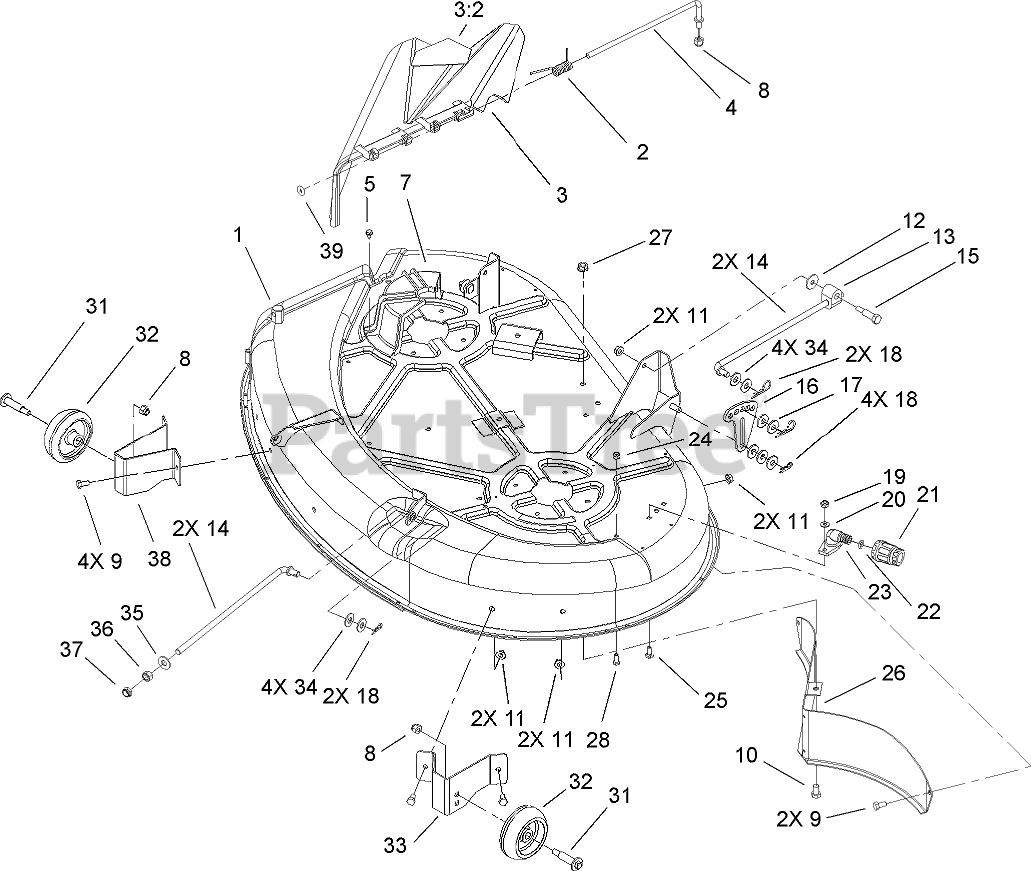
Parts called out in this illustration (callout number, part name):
1	42 INCH DECK ASM
2	SPRING
3	42 INCH DEFLECTOR ASM
3:2	DECAL-DANGER, SHIELD
4	ROD-PIVOT
5	SCREW-HWHTF
7	GUIDE-BELT, RH
8	NUT-LOCK, NI
9	SCREW-HH
10	SCREW-HH
11	NUT-HF
12	WASHER-PIVOT
13	TRUNNION-HOC
14	ROD-HANGER
15	SCREW-SHOULDER, HH
16	LINK-ADJUSTING, HOC
17	WASHER-HARDENED
18	PIN-HAIR
19	NUT-LOCK, NI
20	WASHER-FLAT
21	CONNECTOR-HOSE
22	O-RING
23	FITTING-WASHOUT
24	NUT-LOCK, NI
25	BOLT-CARR
26	BAFFLE-REAR
27	NUT-HF
28	SCREW-HH
31	SCREW-SHOULDER, HWH
32	WHEEL-GAGE
33	BRACKET-GAGE WHEEL, FRONT (LH)
34	WASHER-FLAT
35	WASHER-FLAT
36	NUT-HEX
37	NUT-LOCK, NI
38	BRACKET-GAGE WHEEL, FRONT (RH)
39	O-RING
